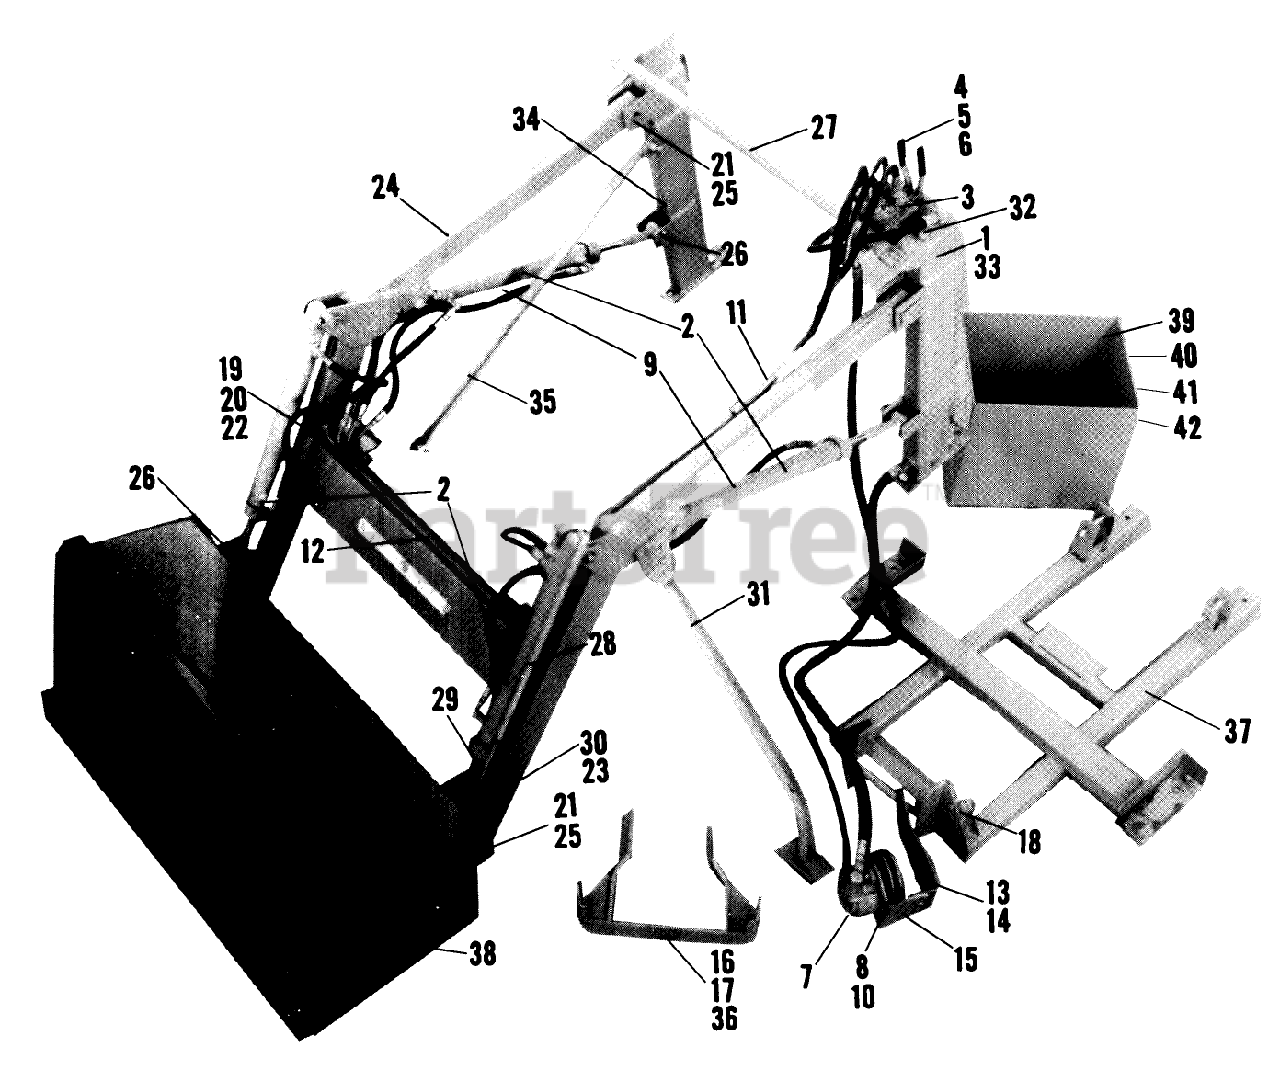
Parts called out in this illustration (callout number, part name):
1	Caution Decal
2	Lift Tilt Cylinder
3	Control VaIve
4	Handle Linkage
5	Valve Handle
6	Black Vinyl Cover
7	Retainer-Spring
8	Pulley
9	52014/15/90A RER 34
10	Gates V-Belt 6827
11	Hydraulic MetaI Line-Arm
12	Self Tapping Screw
13	Bushing-Stator
14	Pump Mounting Support Plate
15	Pump Mounting Bracket
16	Left Hose Bracket (Front Mounting)
17	Right Hose Bracket (Front Mounting)
18	Key-Timing
19	Hydraulic Line Hold Down
20	Hydraulic Line Bracket
21	Grease Fitting
22	Foam Cushion
23	Spacer/Bushing
24	Boom Assembly
25	Pivot Pins-Boom to Bucket Boom to Uprights
26	Cylinder Attaching Pin
27	Cross Tie
28	Guide Tube
29	Guide Rod
30	Tapped Pivot Pin
31	Parking Stand
32	Breather Cap
33	Upright LH
34	Upright Assembly (Right)
35	Brace Arm
36	Front Mounting Assembly
37	Underframe Assembly
38	Bucket Assembly
39	Ballast Box
40	Ballast Box Bracket
41	Ballast Box Hitch
42	Ballast Box Door
